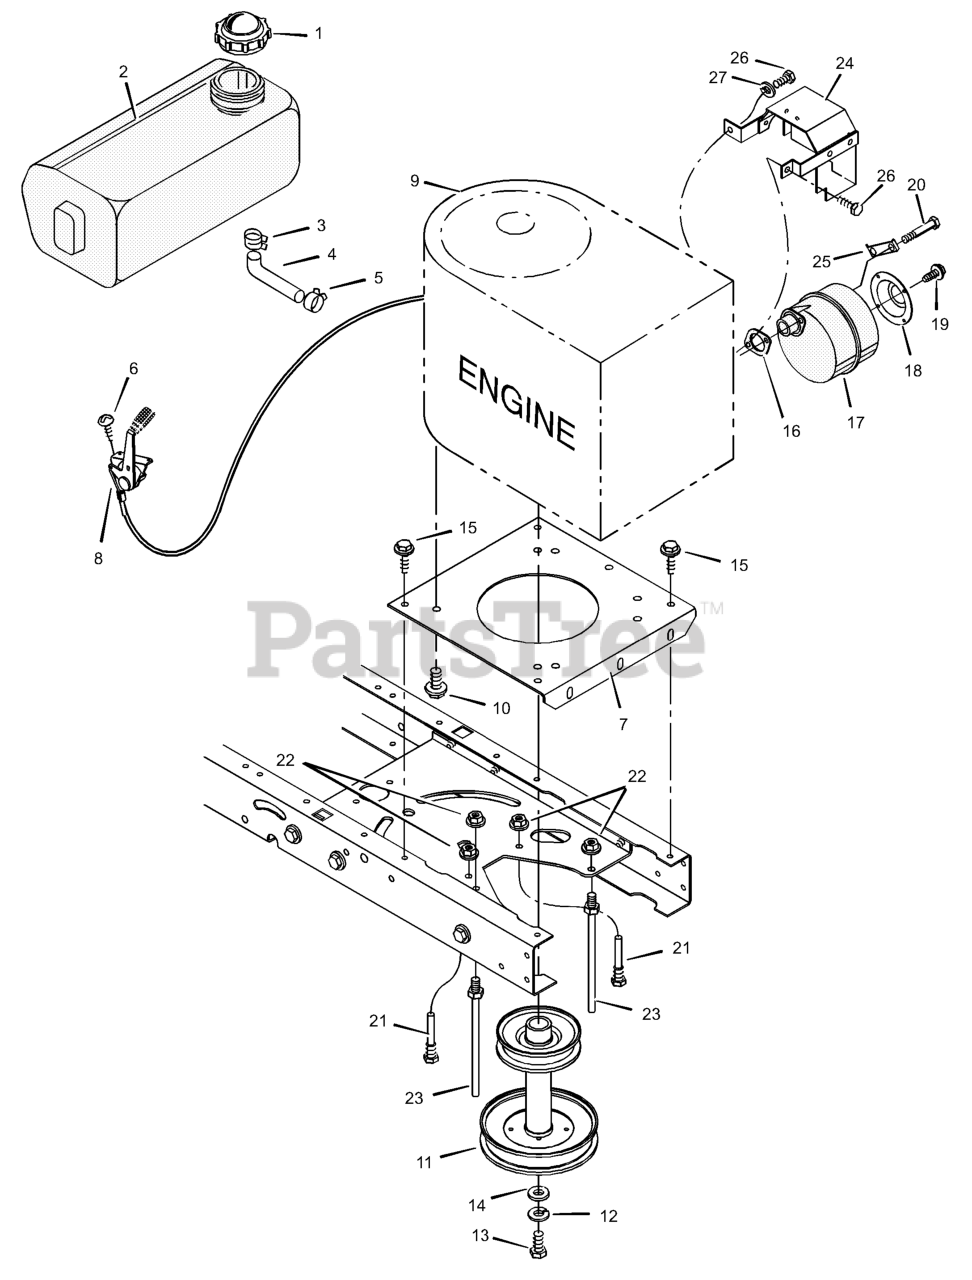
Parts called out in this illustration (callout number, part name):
1	Fuel Cap
2	Fuel Tank
3	Hose Clamp
4	Fuel Line (must cut to length)
5	Hose Clamp
7	Plate, Engine
8	Throttle Control
9	Engine *
10	Bolt, Engine Mount
11	STACK PULLEY ASSEMBLY
12	Lockwasher
13	Bolt, Hex
16	GASKET, Exhaust
17	Muffler
18	Deflector, Muffler
20	Bolt, Hex
21	Guide, Belt
22	Nut, Flange
23	Guide, Belt
24	Shield, Heat
25	Lock, Screw
